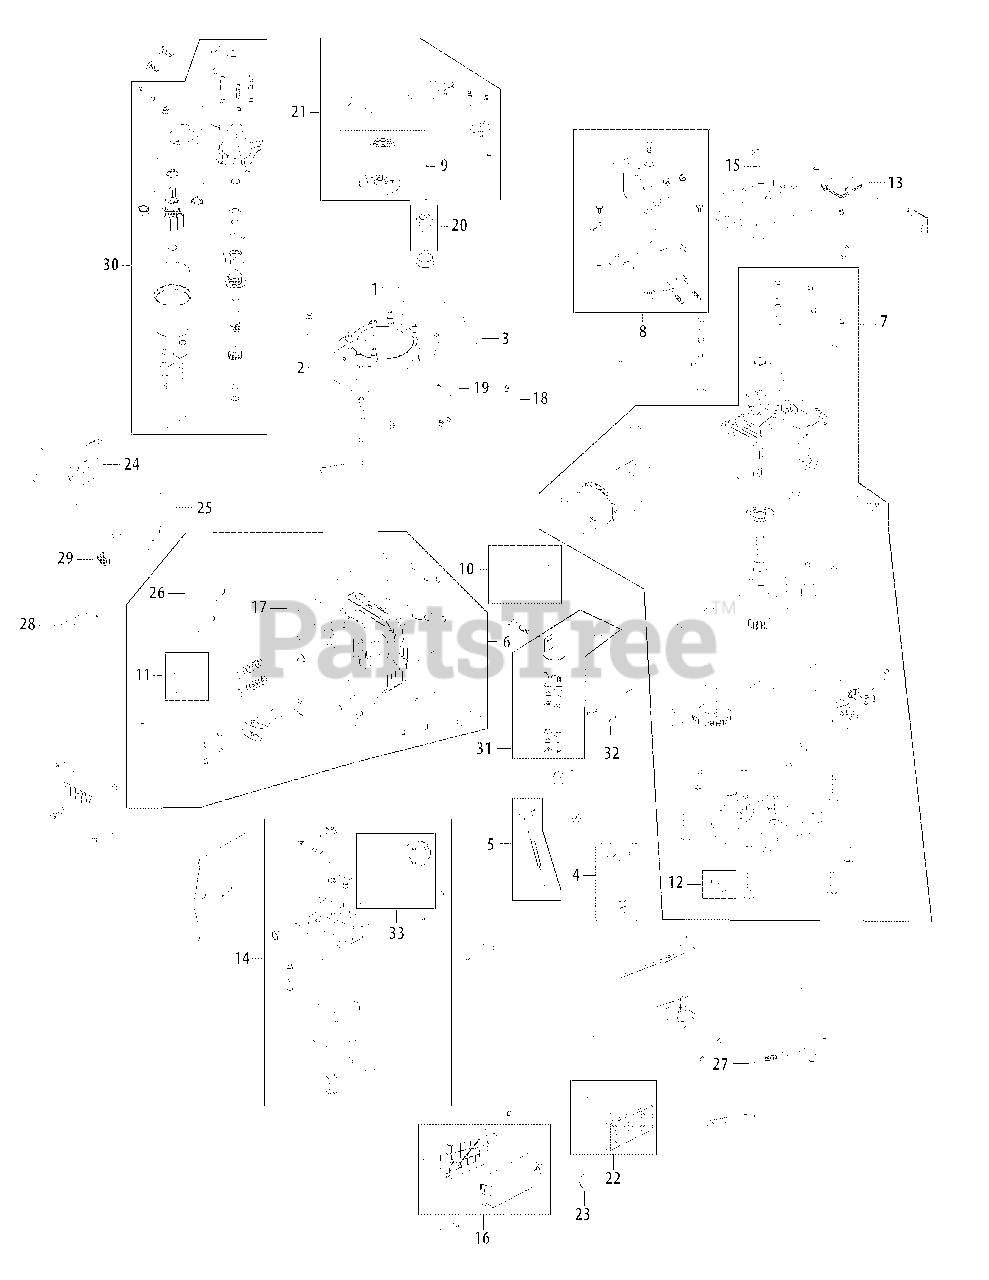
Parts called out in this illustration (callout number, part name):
1	Fuel Tank
2	Flywheel Shroud
3	Rubber Fuel Tank Washer
4	Oil Filler Tube
5	Dipstick Assembly
6	Cylinder Head Assembly
7	Short Block Assembly
8	Stop Switch Brake Assembly
9	Recoil Spring & Pulley Assembly
10	Push Rod Kit
12	Oil Drain Plug and Washer Assembly
13	Ignition Coil
14	Carburtor Assembly
15	Flywheel Key
16	Air Cleaner Housing Complete
17	Muffler Stud Assembly
18	Fuel Line Kit
19	Fuel Filter
20	Fuel Cap Assembly
21	Recoil Starter Assembly
22	Air Cleaner Kit
23	Air Cleaner Thumb Screw
24	Muffler Guard
26	Muffler Gasket & Heat Shield
27	Governor Return Spring
28	Spark Plug
29	Spark Arresstor
30	Electric Starter
31	Relay Assembly
32	Relay Harness Connector
33	Primer Assembly
